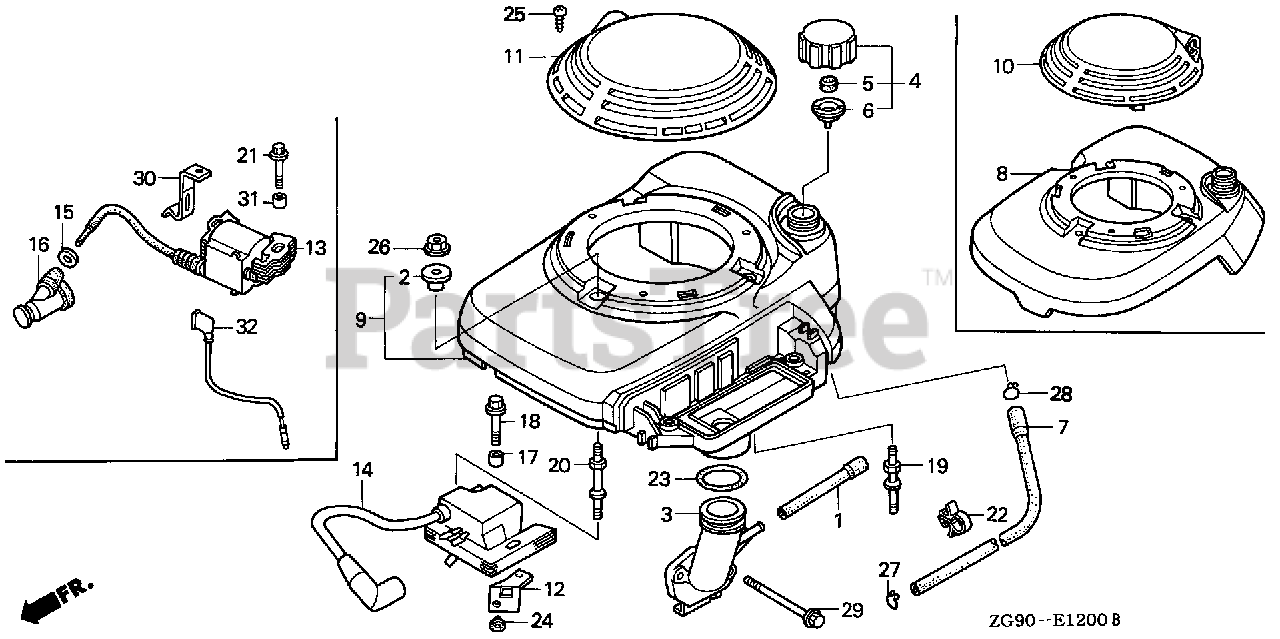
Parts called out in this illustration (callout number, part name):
1	TUBE, BREATHER (180MM)
2	COLLAR, AIR CLEANER (TOYO ROKI)
3	ELBOW, AIR CLEANER
4	CAP ASSY., FUEL TANK
5	SPONGE, FUEL CAP BREATHER
6	GASKET, FUEL CAP
7	TUBE, FUEL TANK (280MM)
9	COVER, FAN *R8* (BRIGHT RED)
9	COVER, FAN *NH1* (BLACK)
9	COVER, FAN *NH164* (GRIP GRAY)
9	COVER, FAN *R280* (POWER RED)
11	HOOD, FAN COVER *NH1* (GRAINED FINISH) (BLACK)
11	HOOD, FAN COVER *R8* (GRAINED FINISH) (BRIGHT RED)
11	HOOD, FAN COVER *NH164* (GRAINED FINISH) (GRIP GRAY)
11	HOOD, FAN COVER *R280* (GRAINED FINISH) (POWER RED)
14	COIL ASSY., IGNITION
17	COLLAR, ROTO-STOP
18	BOLT, FLANGE (6X32)
19	BOLT, STUD (BRAKE)
20	BOLT C, STUD
22	CLIP B, CABLE (9MM BLACK)
23	O-RING (33.3X3.5)
25	SCREW, TAPPING (4X20)
26	NUT, FLANGE (6MM)
27	CLIP, TUBE (B8)
28	CLIP, TUBE (B10)
29	BOLT, FLANGE (6X100)
